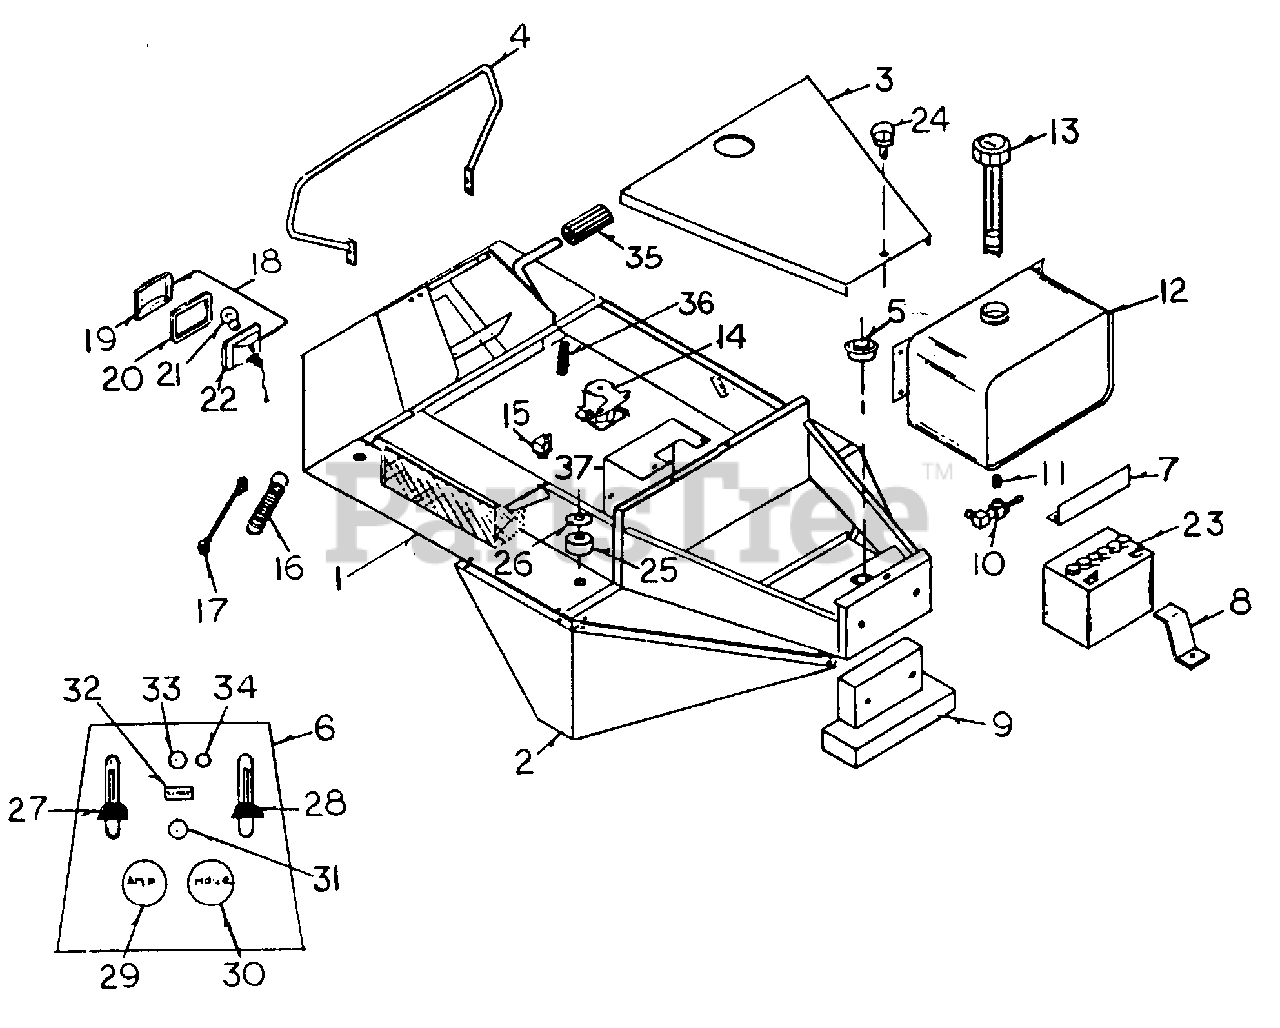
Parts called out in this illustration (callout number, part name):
1	Body
2	Fender, LH
7	Hold Down, Battery
8	Battery Post Protector
9	Tail Weight
10	Shutoff Valve, Fuel
11	Nlpple, 1/8" x Close
13	Fuel Tank Cap w/Gauge
15	Relay
17	Deck Llft Cable
18	Llght Assembly
19	Lens
20	Gasket
21	Bulb
23	Battery
25	Rubber Body Mount
26	Body Mount Washer
28	Throttle Cable
31	Ignltion Switch
32	Light Switch
33	Clutch Switch
35	Brake Pedal Pad
36	Spring
37	Oil Tank Mount
